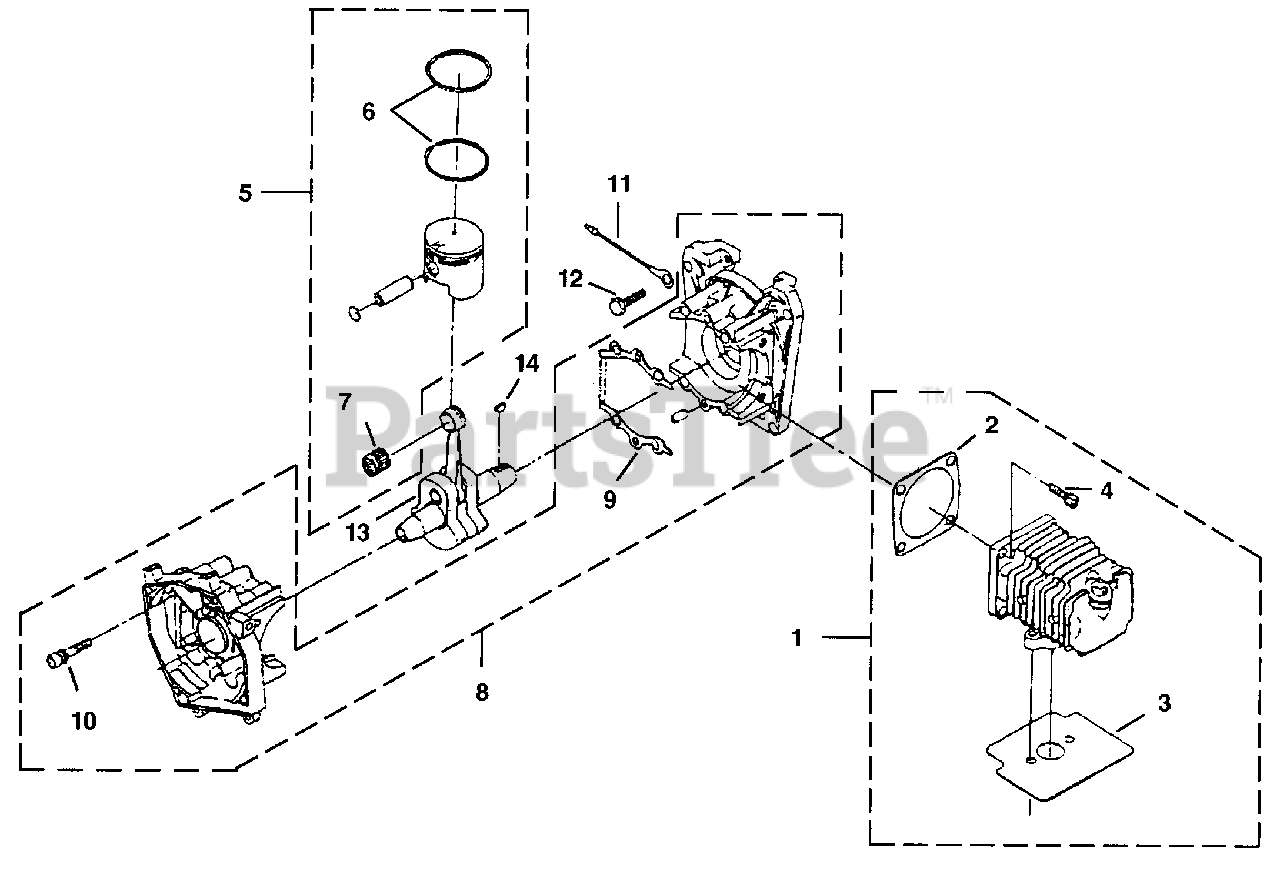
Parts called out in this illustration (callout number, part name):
1	CYLINDER ASSEMBLY
2	GASKET-Cylinder
3	GASKET-Muffler
4	SCREW-Socket Hd (M6 x 18)
5	PISTON ASSEMBLY
6	RING-Piston
7	BEARING-Wrist Pin
8	CRANKCASE ASSEMBLY
9	GASKET-Crankcase
10	SCREW-Socket Hd (M5 x 30 SW)
11	WIRE-Ground
12	BOLT ASSEMBLY (M6 x 25 SW)
13	CRANKSHAFT COMPLETE
14	WOODRUFF KEY
